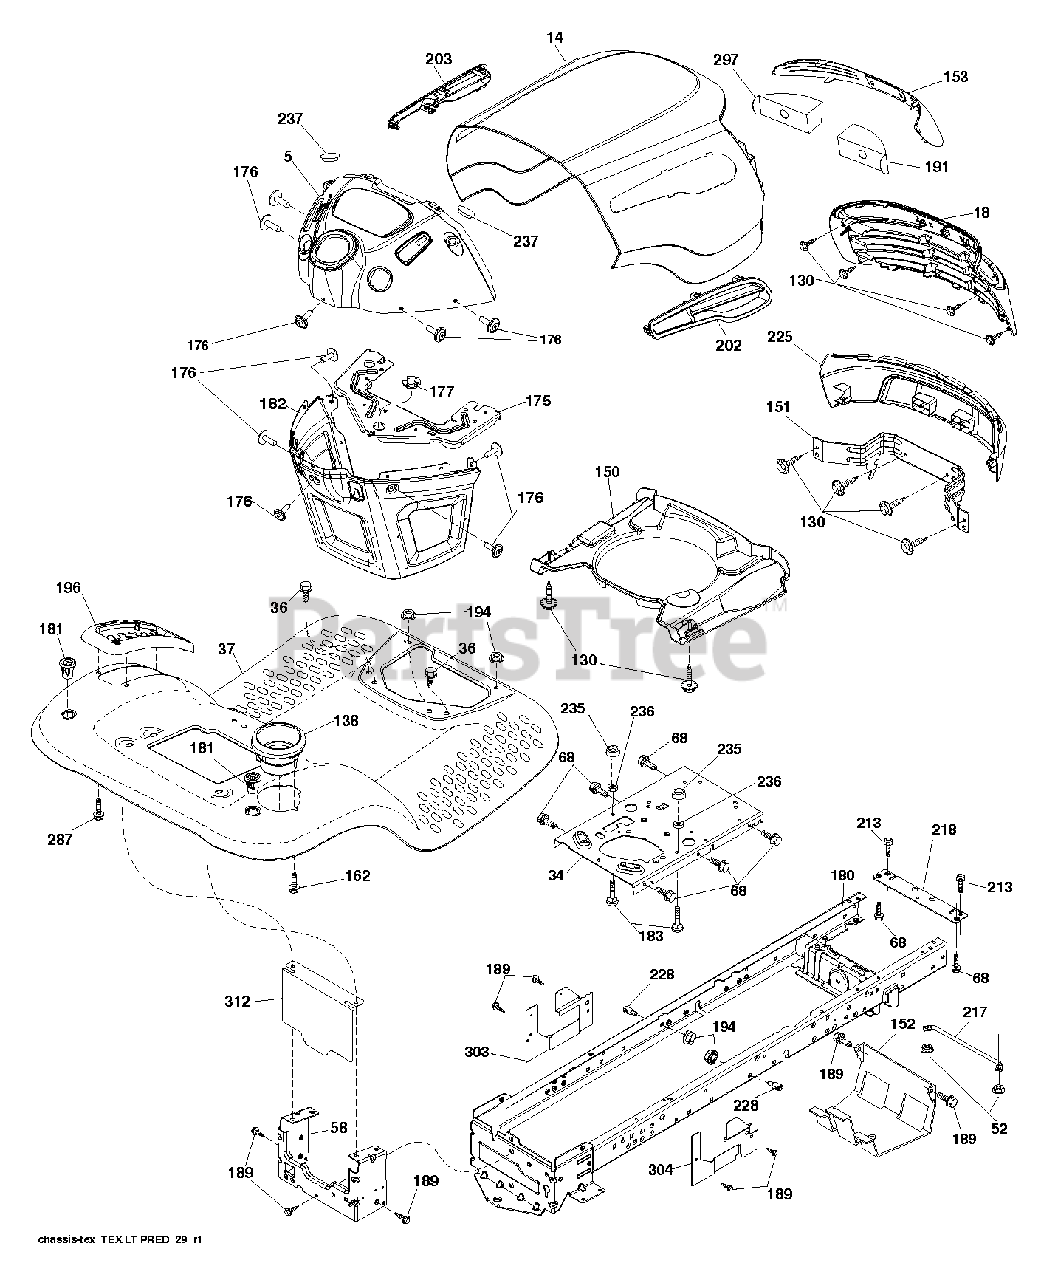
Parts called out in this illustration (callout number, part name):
34	PLATE.ENGINE.WELDED.CHASSIS
36	SCREW 5/16"
52	LOCKNUT
58	DRAWBAR UPPER 2PC SMALL FENDER
130	SCREW.#10 X 0.750.BOS THREAD
138	CUPHOLDER.TL.TEX.BLACK
151	BRACKET.PIVOT.ALPHA.LT
152	SHIELD BROWNING
162	SCREW.HI-LO.CONSOLE
175	CROSSMEMBER
176	SCREW.#10-24X5/8.RN.QU
177	BUSHING STEERING
181	FEND/FTRST.PCH.CPH.NFW
182	DASH.LWER.PREDATOR/HUSQ.LT
183	BOLT.5/16-18X1-1/4 FULL.THREAD
189	SCREW
191	INSERT.REFLECT.PREDATOR.LT.RH
194	NUT LOCK HEX FLANGE 5/16-18
196	CONSOLE.ASM.DECKLFT.BL/RBT.TLT
213	BOLT
217	ROD.PIVOT.HOOD
218	X-PIECE.HOOD.STOP.NON/
228	STUD.FASTNER.W/ANTI-ROTATE
235	SPACER FENDER
236	NUT.CENTERLOCK.5/16-
237	PLUG.MOUNT.CARGO.BLK
297	REFLECTOR.INSERT.PRED.LH.LT
